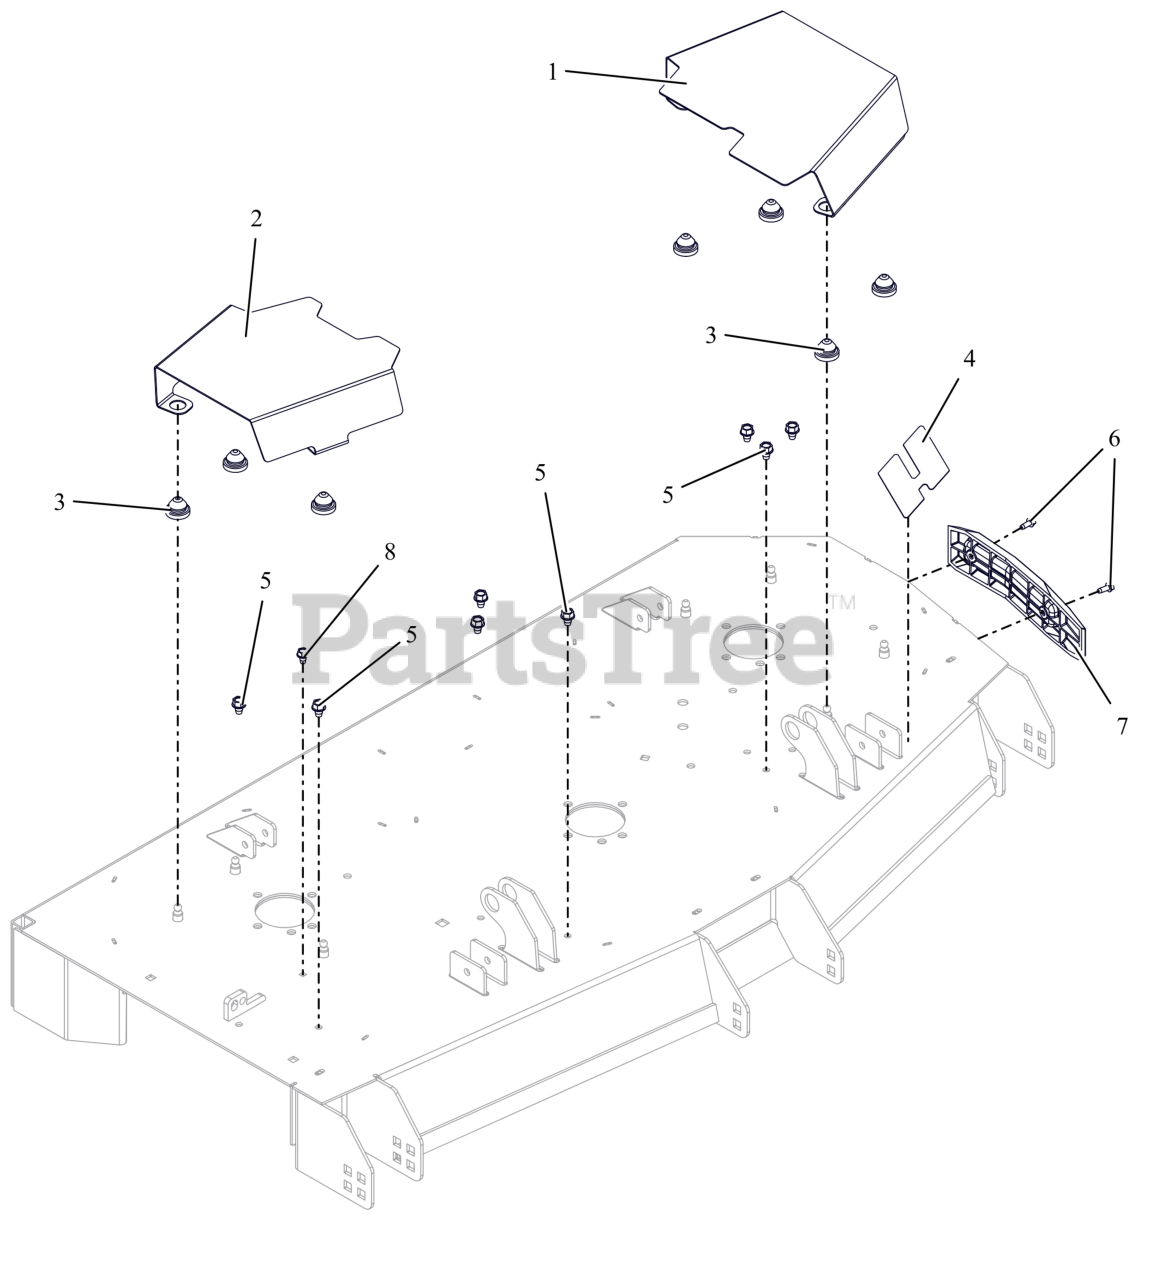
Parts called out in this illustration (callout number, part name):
1	COVER- BELT 52" LEFT
2	COVER- BELT 52" RIGHT
3	COUPLING, RUBBER PUSH-IN
4	GRIP- STEP ANTISKID HD STEALTH
5	SCR,TAP .375-16X.50 HWH TR ZCC
6	SCR,TAP .25-20X.625 HWH ZCC
7	BUMPER- DECK
8	SCR,TAP .312-18X.50 HWH TR ZCC
